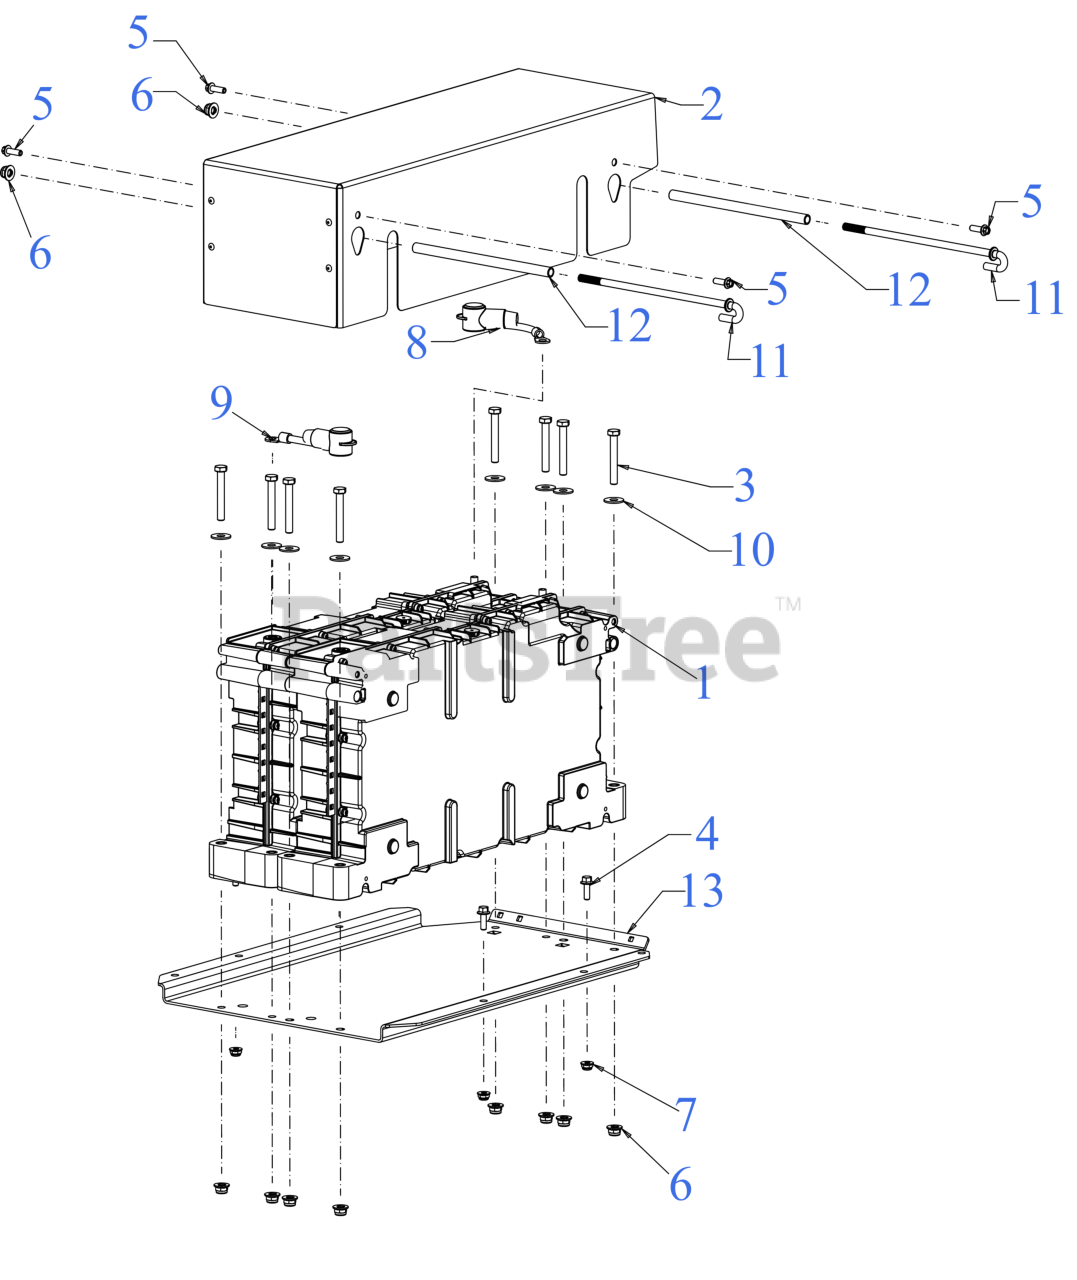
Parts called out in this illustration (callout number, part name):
2	BATTERY COVER
3	HEX SCREW 5/16-18 x 2.25 GR5
4	SCREW 1/4-20 x .75 GR5
5	SCREW 1/4 x .750
6	FLANGE LOCK NUT 5/16-18
7	FLANGE LOCK NUT
8	JUMPER BATTERY HARNESS
9	JUMPER BATTERY HARNESS
10	FLAT WASHER
11	BATTERY ROD
12	SPACER- .322" x .438" x 7.71"
13	BATTERY PLATE BRACKET
